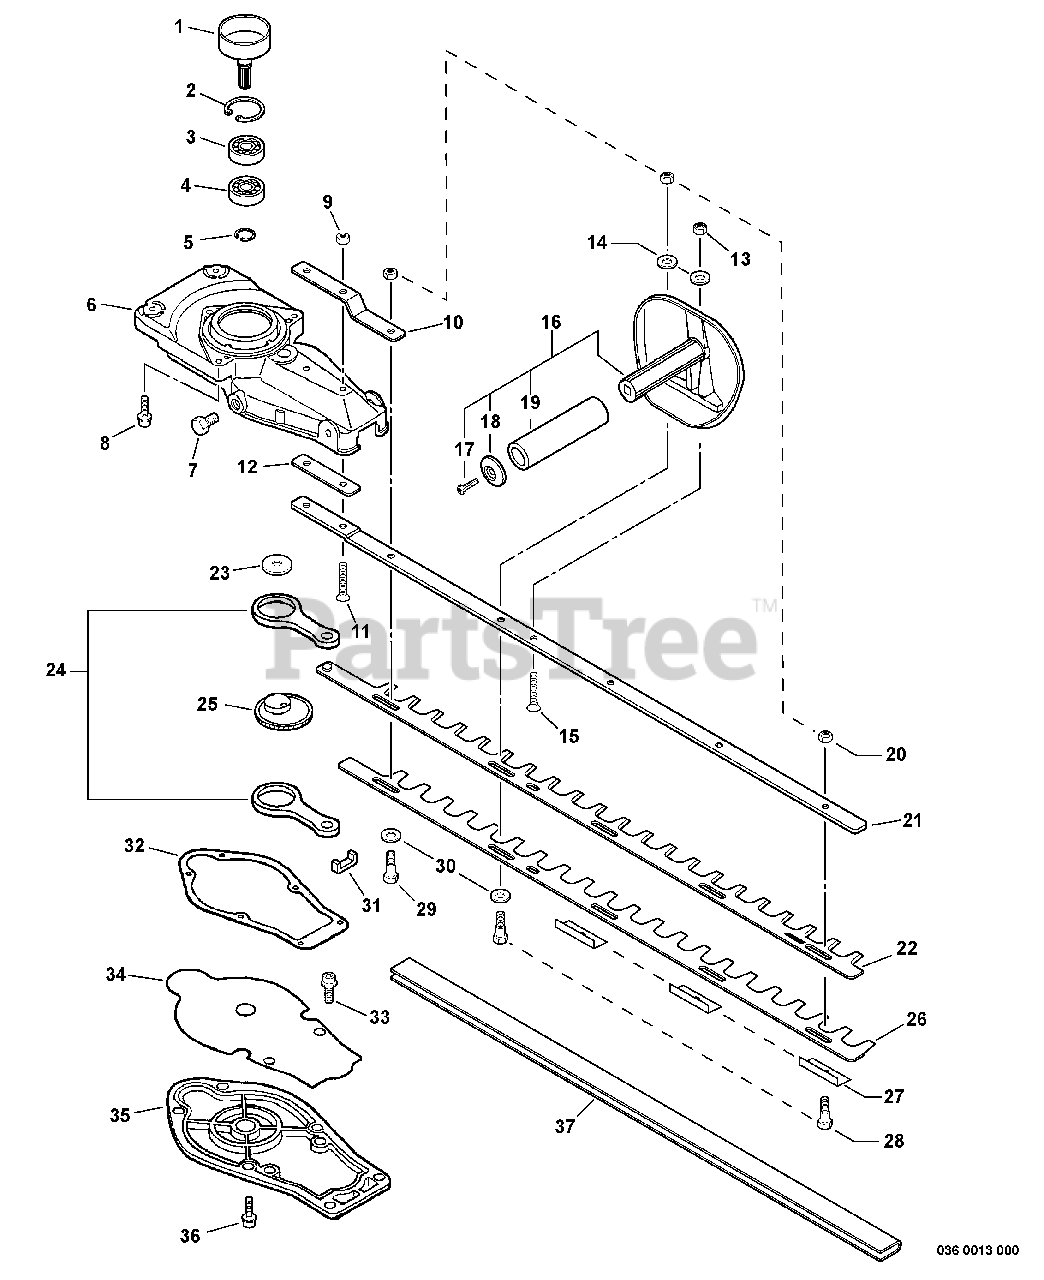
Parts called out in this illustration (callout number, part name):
1	DRUM, CLUTCH
2	RING, SNAP 35
3	BEARING, BALL 6202
4	BEARING, BALL 6202
5	RING, SNAP 14
6	CASE, GEAR
7	BOLT 8×8 SP
8	BOLT 5×25
9	NUT, HEX M6
10	PLATE, ANGLE
11	SCREW 6×25
12	PLATE, EYE
14	WASHER 5.5×18×1
15	SCREW 6×30
16	HANDLE ASSY, FRONT
17	SCREW 5×14
19	GRIP, HANDLE
21	SUPPORT, BLADE
22	CUTTER, UPPER
24	CONROD
26	CUTTER, LOWER
27	INSULATOR
28	BOLT, CUTTER
29	BOLT 6×35
30	WASHER 6.5×15.5×0.6
32	GASKET, GEAR CASE
33	BOLT 5×12
34	PLATE, GEAR CASE
35	COVER, GEAR CASE
36	BOLT 4×12
37	SCABBARD
